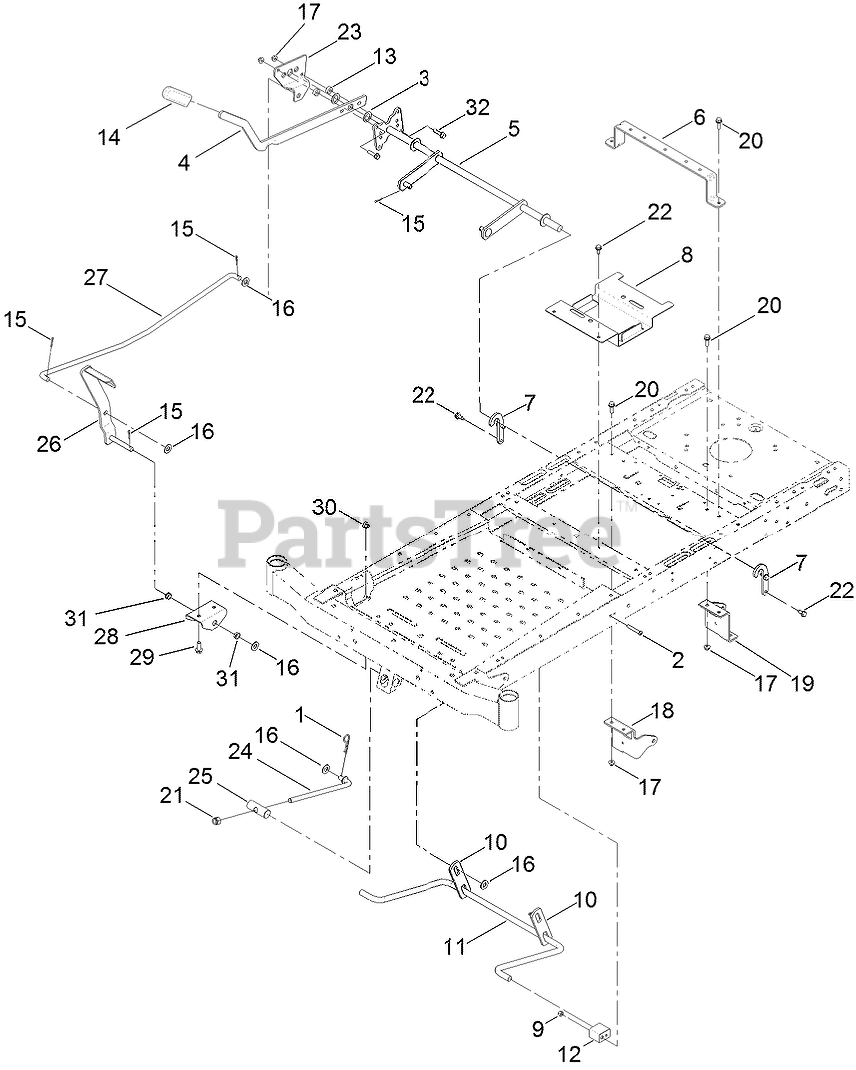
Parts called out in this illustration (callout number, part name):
1	PIN-COTTER
2	SCREW-HSBH
3	WASHER-THRUST
4	LEVER-LIFT
5	LIFT-DECK, WIDE
6	BRACE-SEAT, REAR
7	BRACKET-LIFT
8	BRACKET-BATTERY
9	NUT-LOCK, NI
10	LINK-LIFT
11	ARM-LIFT, REAR (WIDE)
12	BLOCK-PIVOT
13	SPACER
14	GRIP-LEVER
15	PIN-COTTER
16	WASHER-FLAT
17	NUT-HF, NI
18	MOUNT-HYDRO, FRONT (RH)
19	MOUNT-HYDRO, FRONT (LH)
20	SCREW-HHF
21	NUT-HEX
22	SCREW-HWHTF
23	PLATE-FOOTLIFT
24	ROD-TRUNION
25	PIN-PIVOT
27	ROD-FOOTLIFT
28	BRACKET-FOOTLIFT
29	SCREW-HHF
30	NUT-HF, NI
31	BUSHING-FLANGE
32	SCREW-HHF
